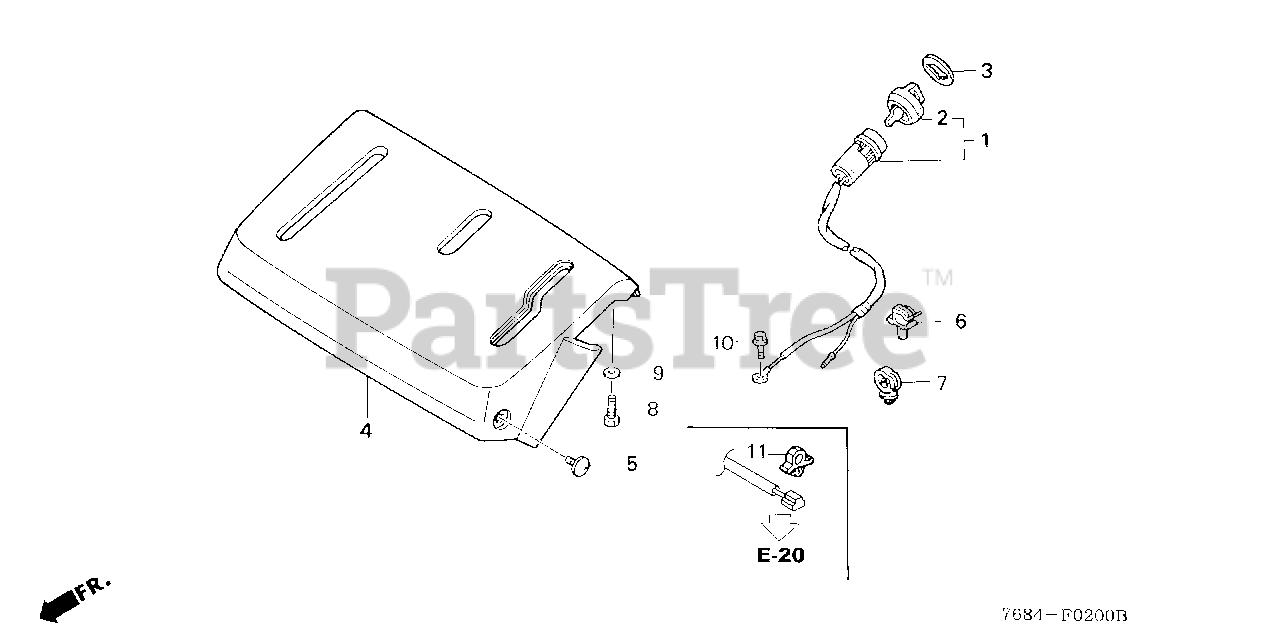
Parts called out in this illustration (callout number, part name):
1	SWITCH ASSY., COMBINATION
2	KEY ASSY., COMBINATION SWITCH (RED)
3	SPACER, ENGINE STOP SWITCH
4	PANEL, CONTROL *NH296* (ALPS GRAY)
5	SCREW, METER VISOR SETTING
5	BOLT, CONTROL PANEL
7	CLIP, WIRE HARNESS (25MM)
8	BOLT, HEX. (5X12)
8	BOLT, FLANGE (5X12)
9	WASHER, PLAIN (5MM)
10	BOLT, FLANGE (6X10)
11	CLIP, IGNITION WIRE (8MM)
